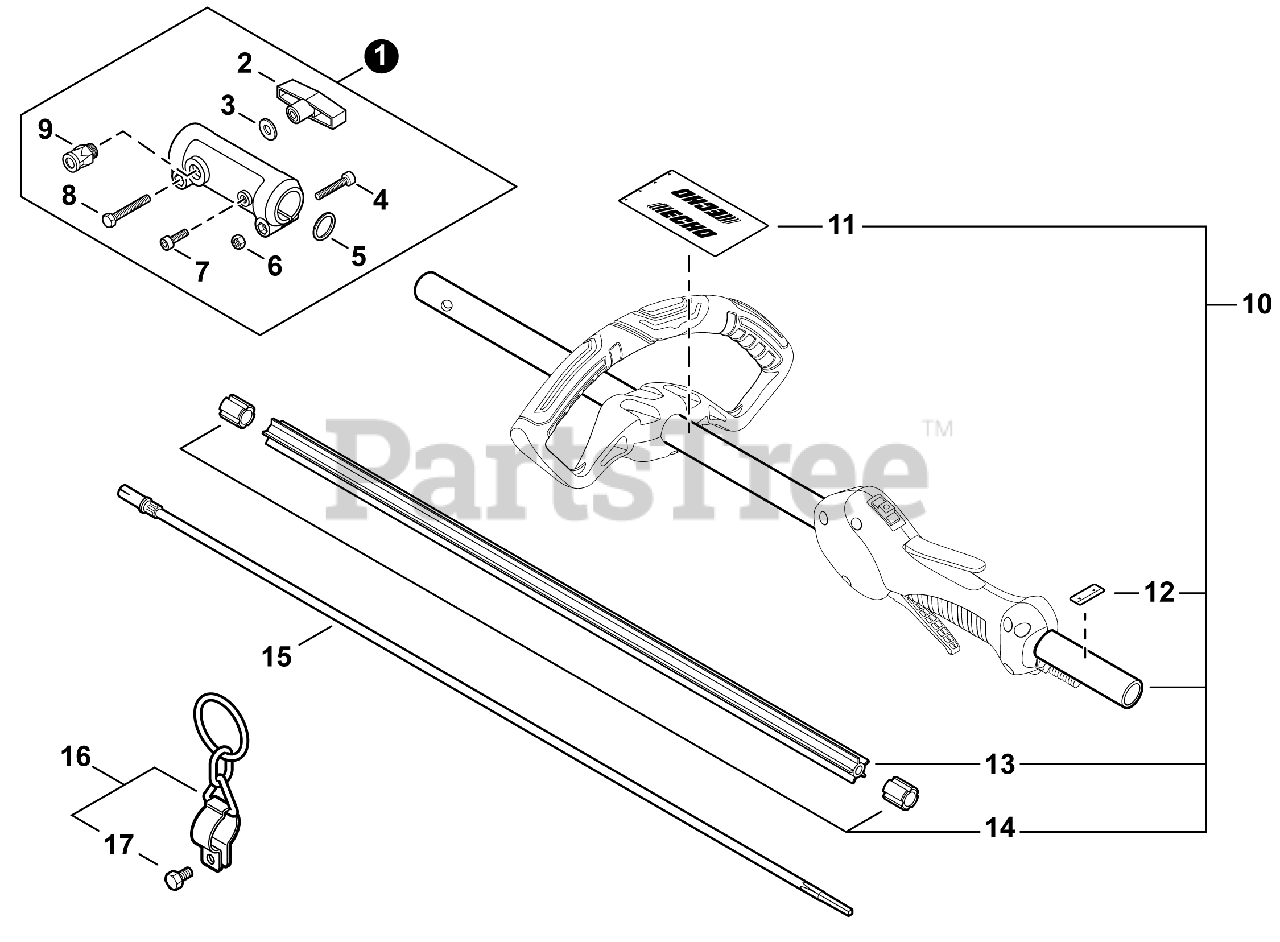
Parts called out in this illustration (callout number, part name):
1	COUPLER ASSY
2	KNOB, FASTENER
3	WASHER 6.6x20x1.6
4	BOLT, TORX 6x25
5	WASHER 18 SPR STEEL
7	BOLT, TORX 5x10
8	BOLT 6x40
9	LATCH ASSY
10	MAIN PIPE ASSY
11	LABEL - HANDLE LOCATION
12	LABEL - ALIGNMENT
13	LINER - FLEXIBLE
15	DRIVESHAFT - FLEXIBLE
16	HANGER SET, HARNESS
17	BOLT 5x12
